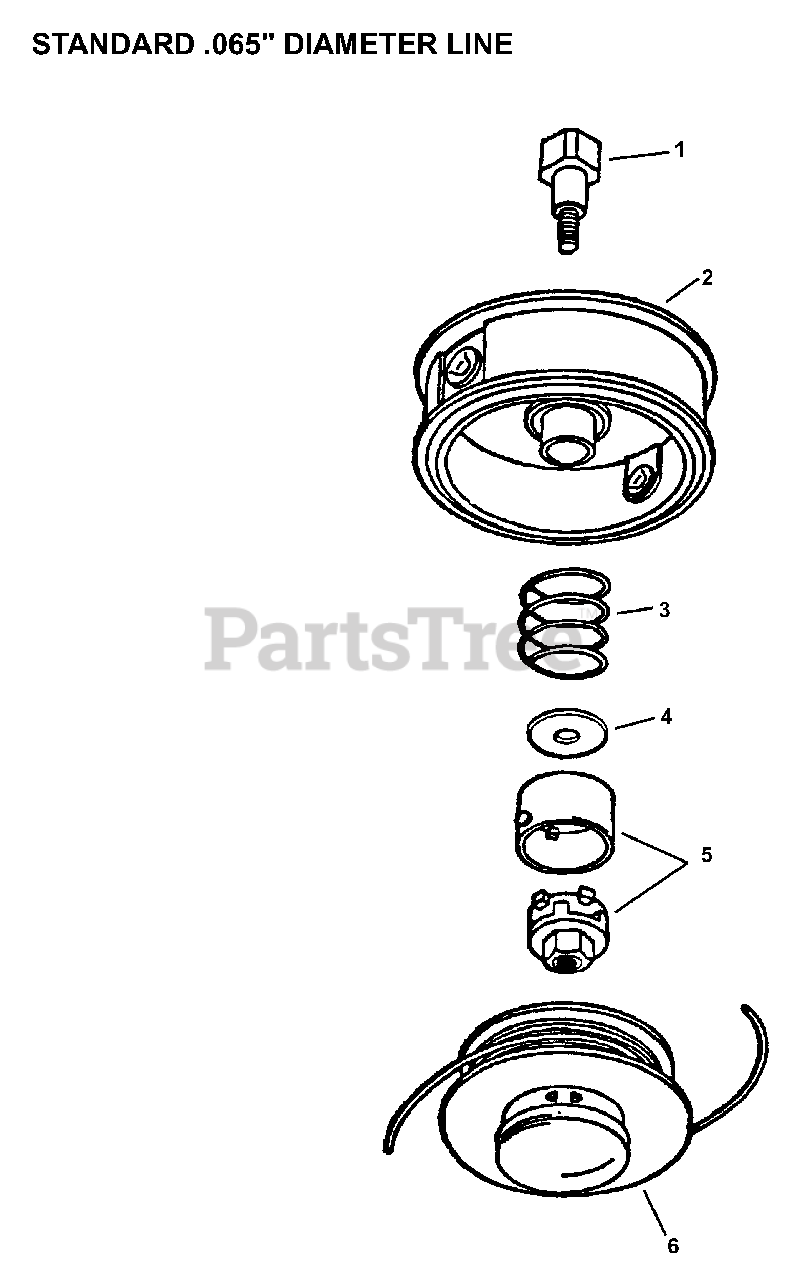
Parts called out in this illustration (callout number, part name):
1	BOLT, SHAFT
2	SPOOL COVER ASSY
3	SPRING
4	WASHER
5	CAM KIT
6	SPOOL
